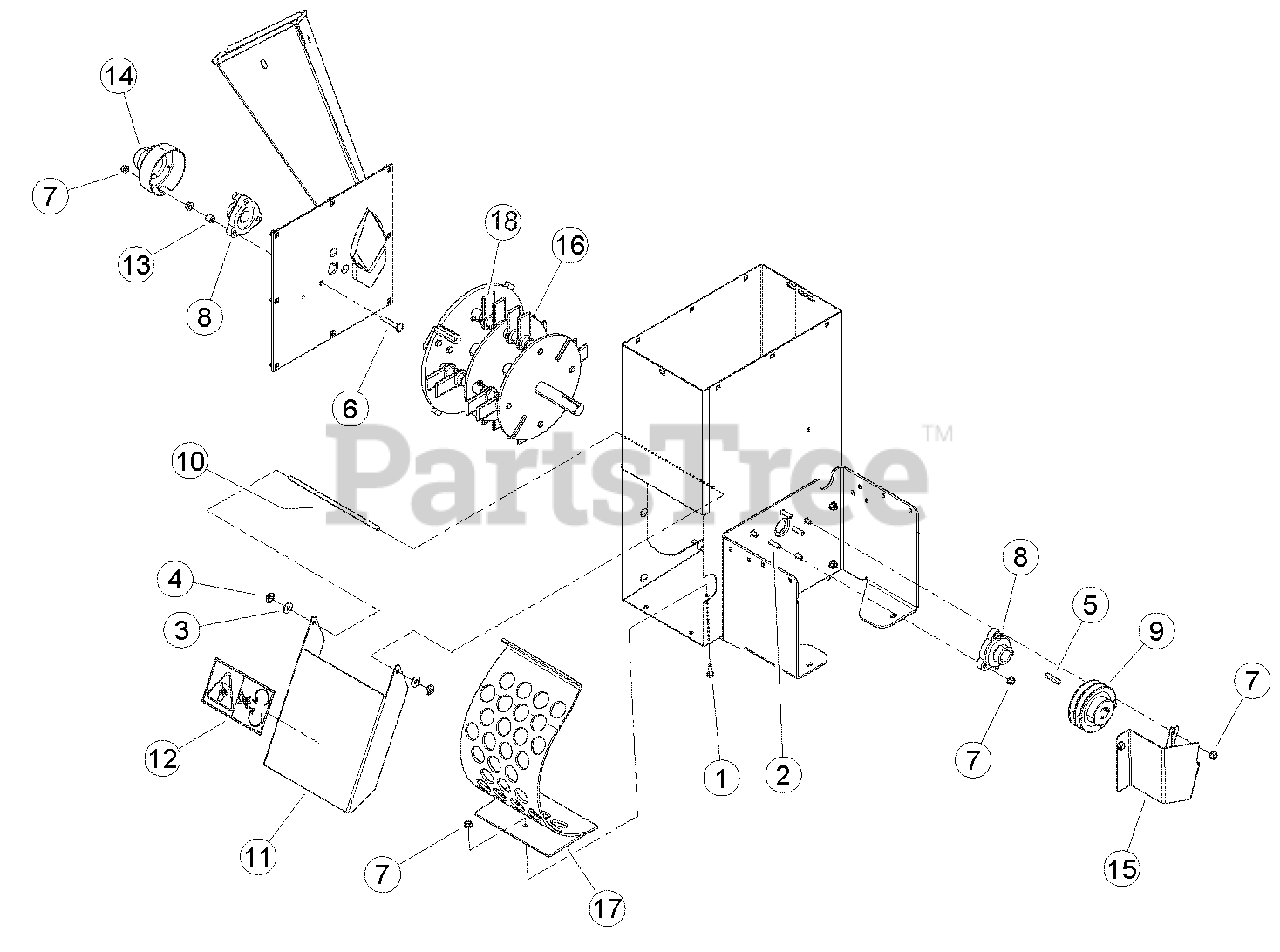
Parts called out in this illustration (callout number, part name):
1	BOLT, 5/16 X 7/8 HEX HD NC GR5 ZP
2	BOLT, 5/16 X 1-1/4 CRG GR5 ZP
3	WASHER, 5/16 ID X 7/8 OD NYLON FLAT
4	PUSHNUT, 5/16 ZP
5	KEY, 1/4 SQUARE X 1-1/2 LONG PLAIN
6	BOLT, 5/16 X 2 CRG GR5 NC ZP
7	NUT, 5/16 FLANGE TOPLOCK
8	BEARING, 1" FLUSHMOUNT CAST W/COLLAR
9	PULLEY, 4X1 2A GROOVE
9	PULLEY, CAST 4" OD,1"BORE,B GRV (SC3206 ONLY)
10	SHAFT, DOOR PIVOT
11	DOOR, 8 HP DISCHARGE, SERVICE PART
11	DOOR, 5 HP DISCHARGE, SERVICE PART - SC3206 ONLY
12	DECAL, BLADE DANGER ISO
13	SPACER .54 OD X .50 LG
14	CAP, ROTOR SHAFT END CAP
15	SHIELD, LOWER
16	ASSEMBLY, BALANCED ROTOR (REPLACED AND SUPERSEDED. FOR SERVICE OF ROTOR ASSEMBLY ORDER KIT #74209-00, ASSEMBLY WITH KNIVES)
16	ASSY, NARROW ROTOR W/ CAST FLAILS (SC3206 ONLY) (REPLACED AND SUPERSEDED. FOR SERVICE OF ROTOR ASSEMBLY ORDER KIT #77591-00, ASSEMBLY WITH KNIVES)
17	WELDMENT, WIDE COARSE TAPERED
17	WELDMENT, NAR. COARSE TAPERED (SC3206 ONLY)
18	SHREDDER FLAIL (REPLACED AND SUPERSEDED. FOR SERVICE ORDER KIT #70973, SHREDDER KNIVES KIT)
18	SHREDDER FLAIL (SC3206 ONLY) (REPLACED AND SUPERSEDED. FOR SERVICE ORDER KIT #77589-00, SHREDDER KNIVES KIT)
